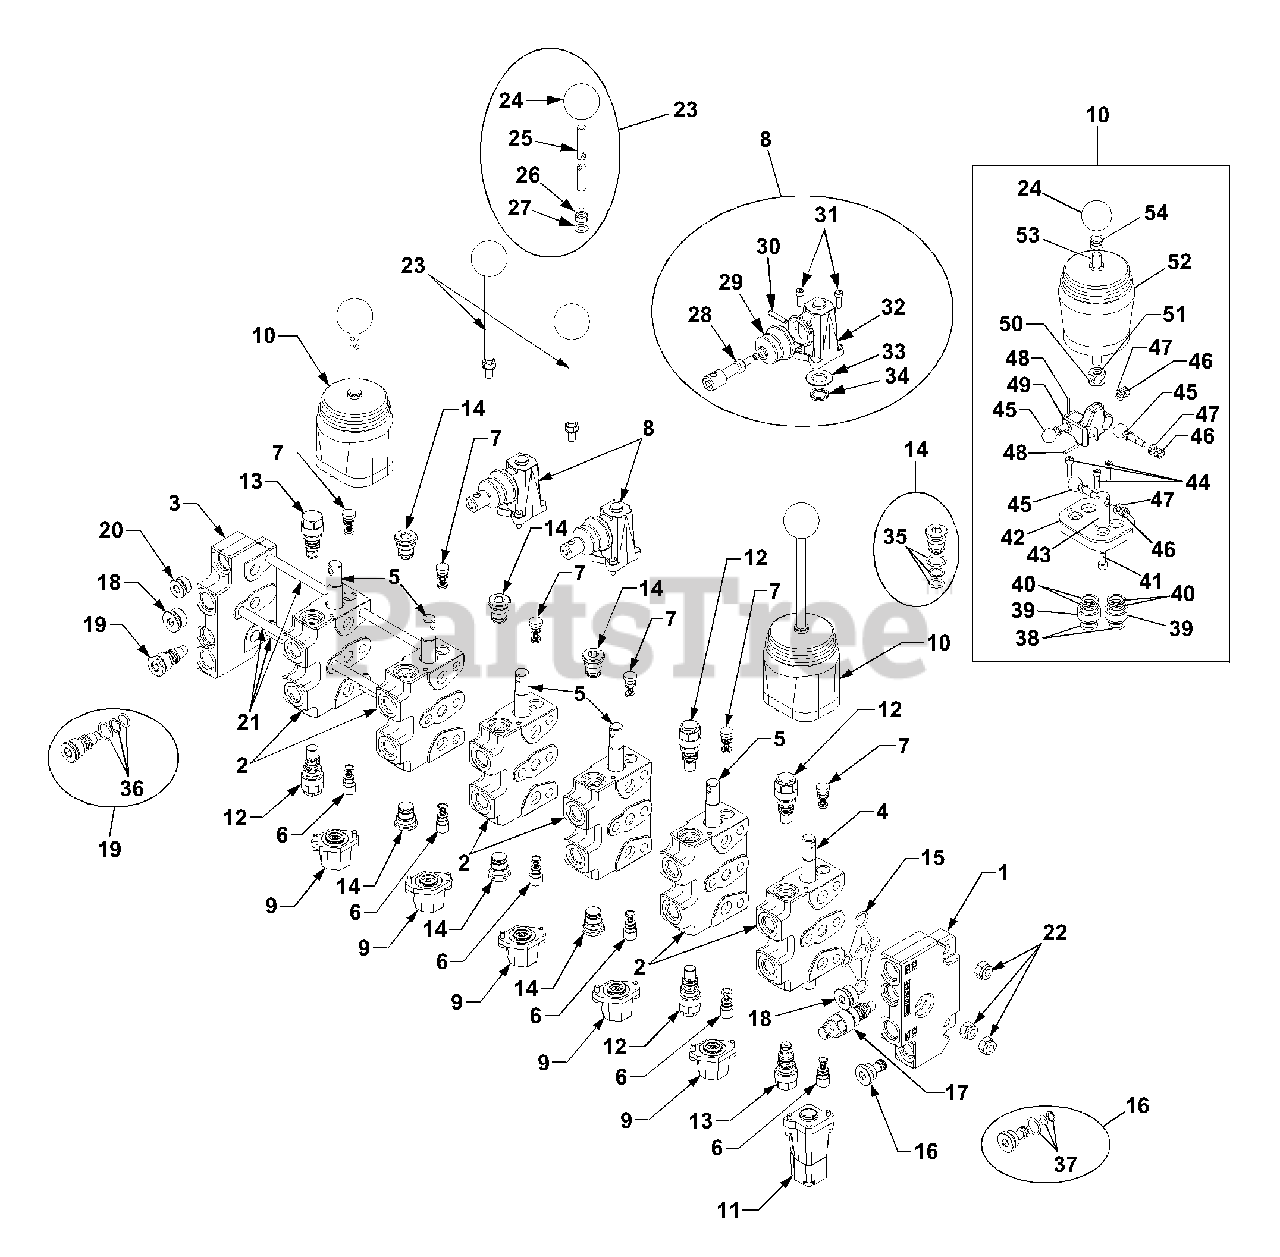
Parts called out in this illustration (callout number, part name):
2	Work Section Body
4	Float, Spool
5	Double Acting Spool
6	Check Valve Ass'y. - A Side
7	Check Valve Ass'y. - B Side
8	Enclosed Lever Ass'y.
9	Spool Control Ass'y.
10	Joystick Ass'y.
11	Spool Control Ass'y.
12	Port Relief Valve Ass'y.
13	Anti Cav. Valve Ass'y.
15	Section Seals
16	Unload Cav. Plug Ass'y.
17	Main Relief Valve Ass'y.
19	Main Relief Cav. Plug Ass'y.
24	Plastic Ball
31	Socket Head Screw, M5
35	Plug Seal Kit (Port Relief)
36	Plug Seal Kit (Main Relief)
37	Plug Seal Kit
40	Joystick Seal Kit
41	Socket Head Screw, M6
43	Joint Foundation Pin
44	Socket Head Screw, M5
53	Lever
54	Rubber Boot Guide
